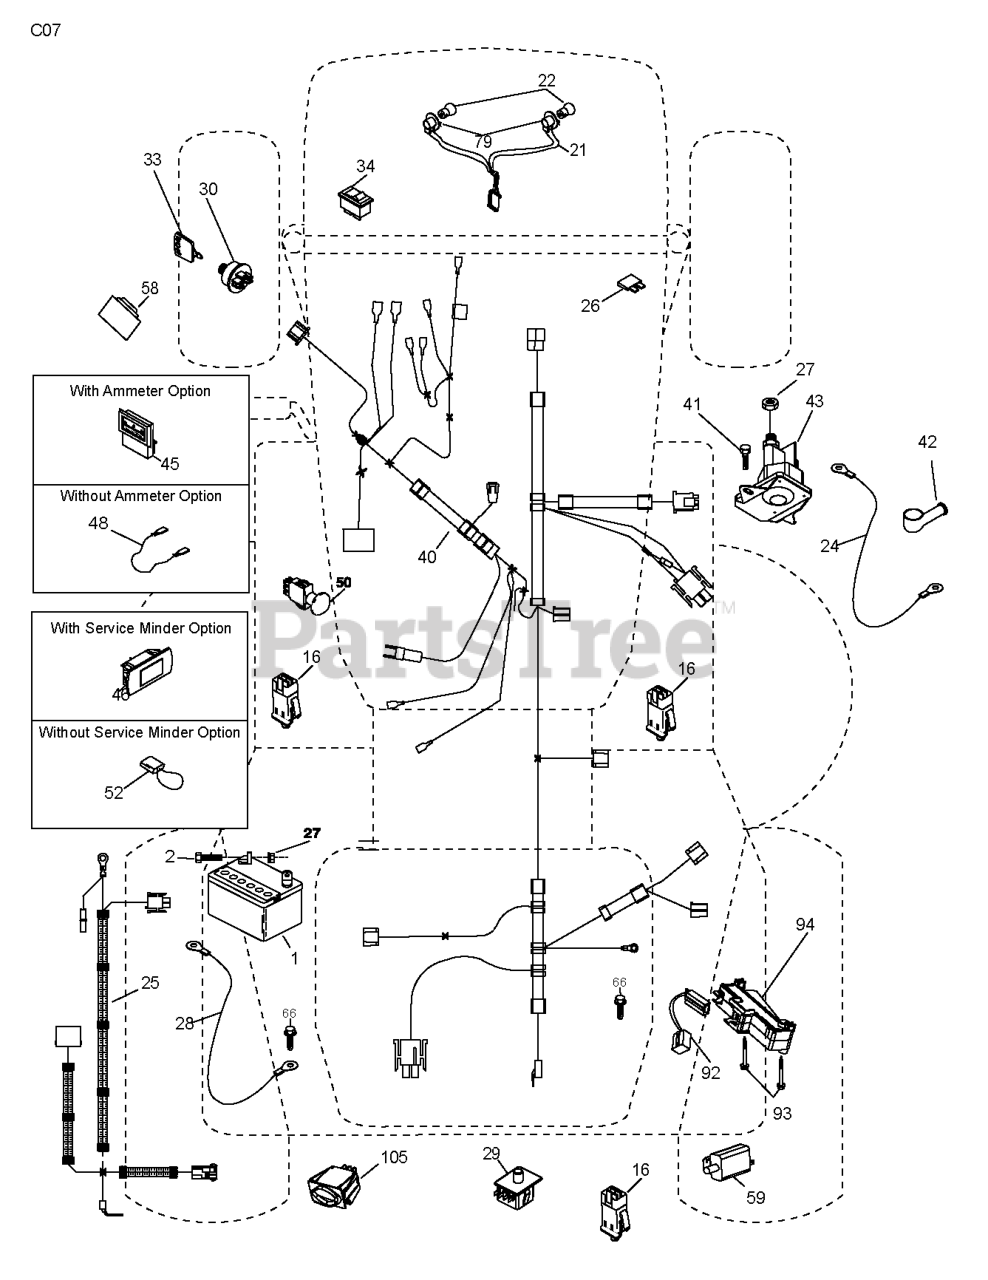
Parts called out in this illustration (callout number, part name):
1	Battery 12 Volt 25 Amp
2	BOLT.HEX.1/4.X.3/4.DICHROMATE
16	SWITCH INTERLOOK PUSH-IN
21	HARNESS ASSY LIGHT
24	CABLE.BATTERY.6GA.16"RED
26	FUSE 20AMP
27	NUT
28	CABLE GROUND
29	SWITCH.SEAT.DP W/RAMPS
30	SWITCH.IGN.DELTA.W.LGH.ROS
33	KEY.CHAIN.BLISTER.PACK.GEN.INT
41	BOLT
42	TERMINAL COVER
43	SOLENOID.W/BRASS.PLUNGER
46	RP.GUAGE.SRVCMNDR.HRMTR.
48	ADAPTER.AMMETER
50	RP.PTO.SWITCH.8 TERMINAL.BLACK
58	BUZZER
59	.WITCH.FULL BAGGER.INDICATOR
79	BULB HOLDER ASM.
92	HARNESS.PIGTAIL.CONSLE
93	SCREW.PLASTITE
94	MODULE.REVERSE.ROS
